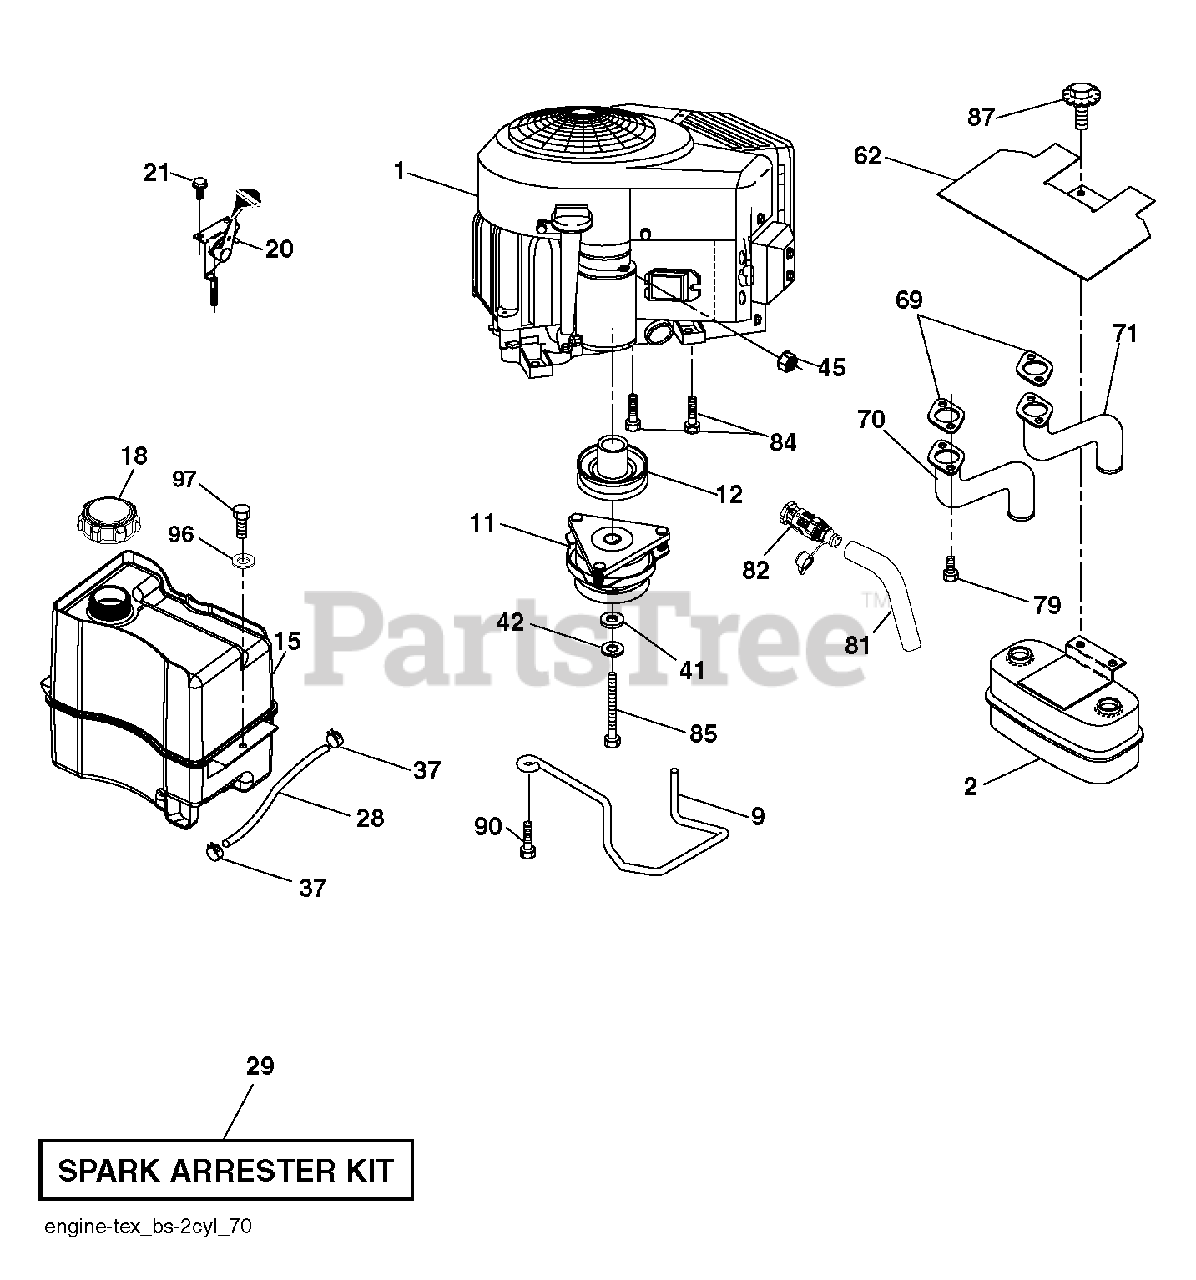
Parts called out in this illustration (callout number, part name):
2	MUFFLER.ASM.TWN.EXTNDED.DFLCTR
9	KEEPER BELT ENGINE
11	CLUTCH.ELECTRIC.LT.48"*
12	PULLEY.ENGINE.TUFFTORQ
15	TANK.ASSEMBL.2.5GAL.NON-EPA
18	CAP ASM.FUEL.2.25"FR.
20	CONTROL.TH/CK.COBRA.B&S.TWN.
21	SCREW.#10 X 0.750.BOS
28	LINE.FUEL.20
29	KIT.SPARK ARRESTOR 794945 B&S
37	HOSE CLAMP
42	LOCKWASHER
45	NUT
62	SHIELD.HEAT.MUFFLER
69	GASKET.MUFFLER
70	EXHAUST.TUBE.LH.BS/TWIN
71	EXHAUST.TUBE.RH.B&S.TWIN.INTEK
79	SCREW.SOCKET.HEAD.5/16-18
81	TUBE, DRAIN OIL ASM.
82	VALUE.OIL.DRAIN
84	SCREW.3/8-16
85	BOLT HEX 7/16-20X4-1/4"
87	Bolt, 5/16-18 X 1-3/4
90	SCREW 3/8-16X1
97	SCREW HEXWSHR 1/4-20X3/4
